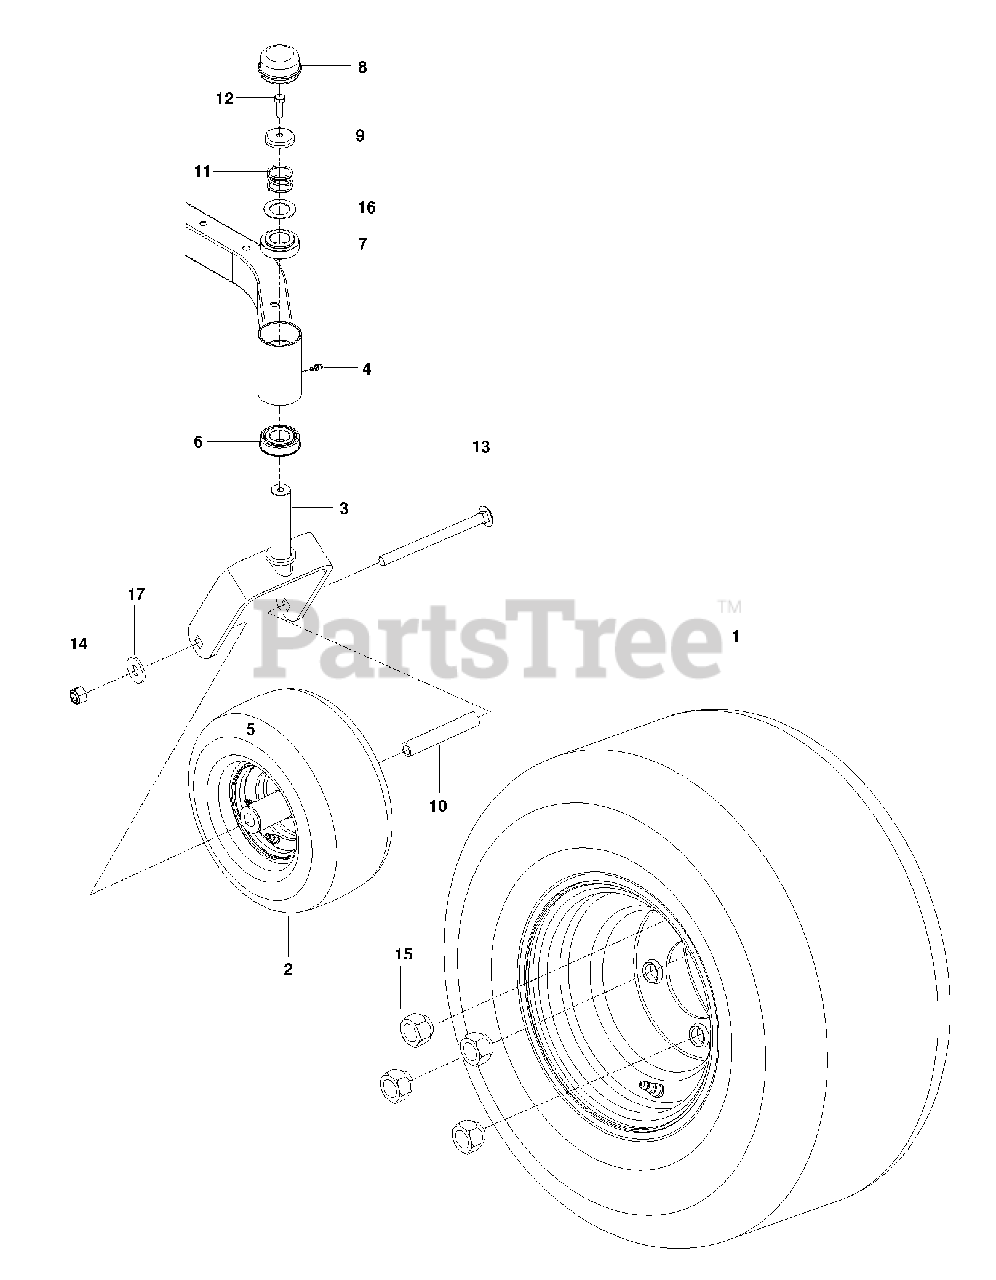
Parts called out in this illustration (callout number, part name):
1	WHEEL.11X4-5.K404LG.5X3W/4.188
2	WHEEL ASSY, WIDE, RZ
3	YOKE, CASTER, WELDMT RAW
4	ZERK, 3/16, DRIVE IN
5	ZERK
6	BEARING FLANGED
7	BUSHING, CASTER
8	GREASE CAP
9	CASTER.PLUG
11	SPRING, CASTER
12	5/16-18X1 HHB G5W/NY
13	RHSNB 1/2-13 X 7.5
14	NUT 1/2-13 HEX CNTRLK GR 5 ZD
15	LUG NUT 1/2F
16	WASHER, 1.025 ID X 1.64
17	WASHER.9/16 X 1 3/8 X 12 GA.
